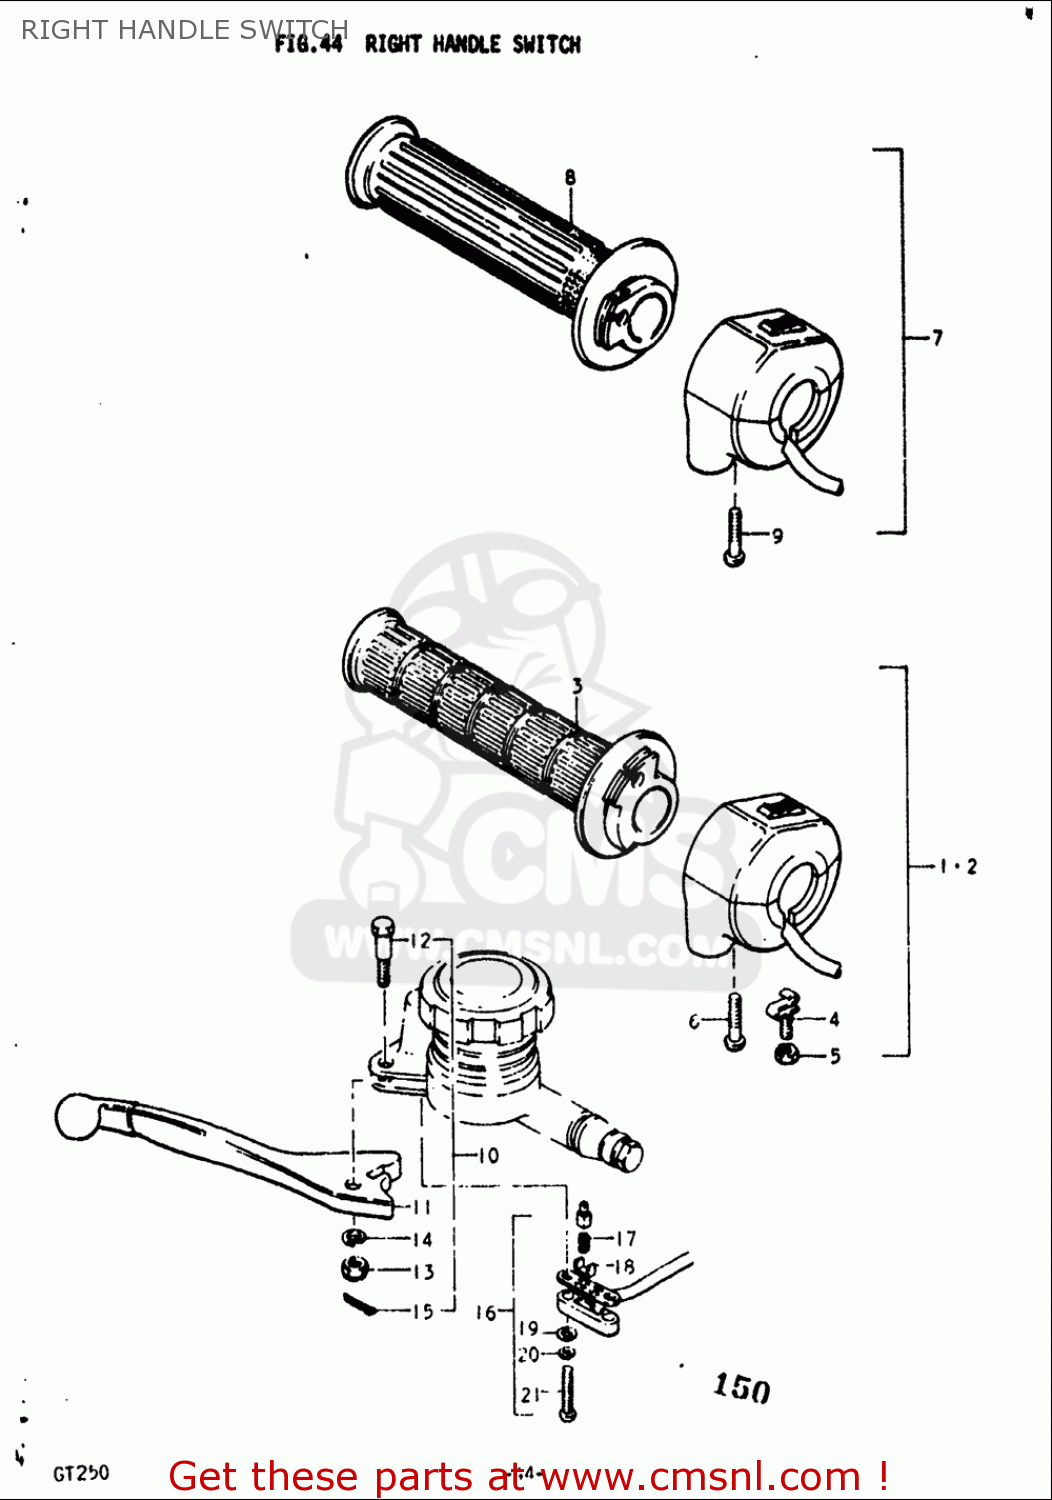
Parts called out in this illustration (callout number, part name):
3	GRIP,THROTTLE
4	ADJUSTER, THROTTLE
5	NUT
6	SCREW
9	SCREW
11	LEVER,BRAKE
12	BOLT
13	NUT,LEVER FITTNG
14	WASHER,LOCK
15	PIN 16X20
16	SWITCH ASSY,STOP
17	CONTACT,SWITCH
18	CONTACT,SWITCH
19	WASHER
20	WASHER,LOCK
21	SCREW
